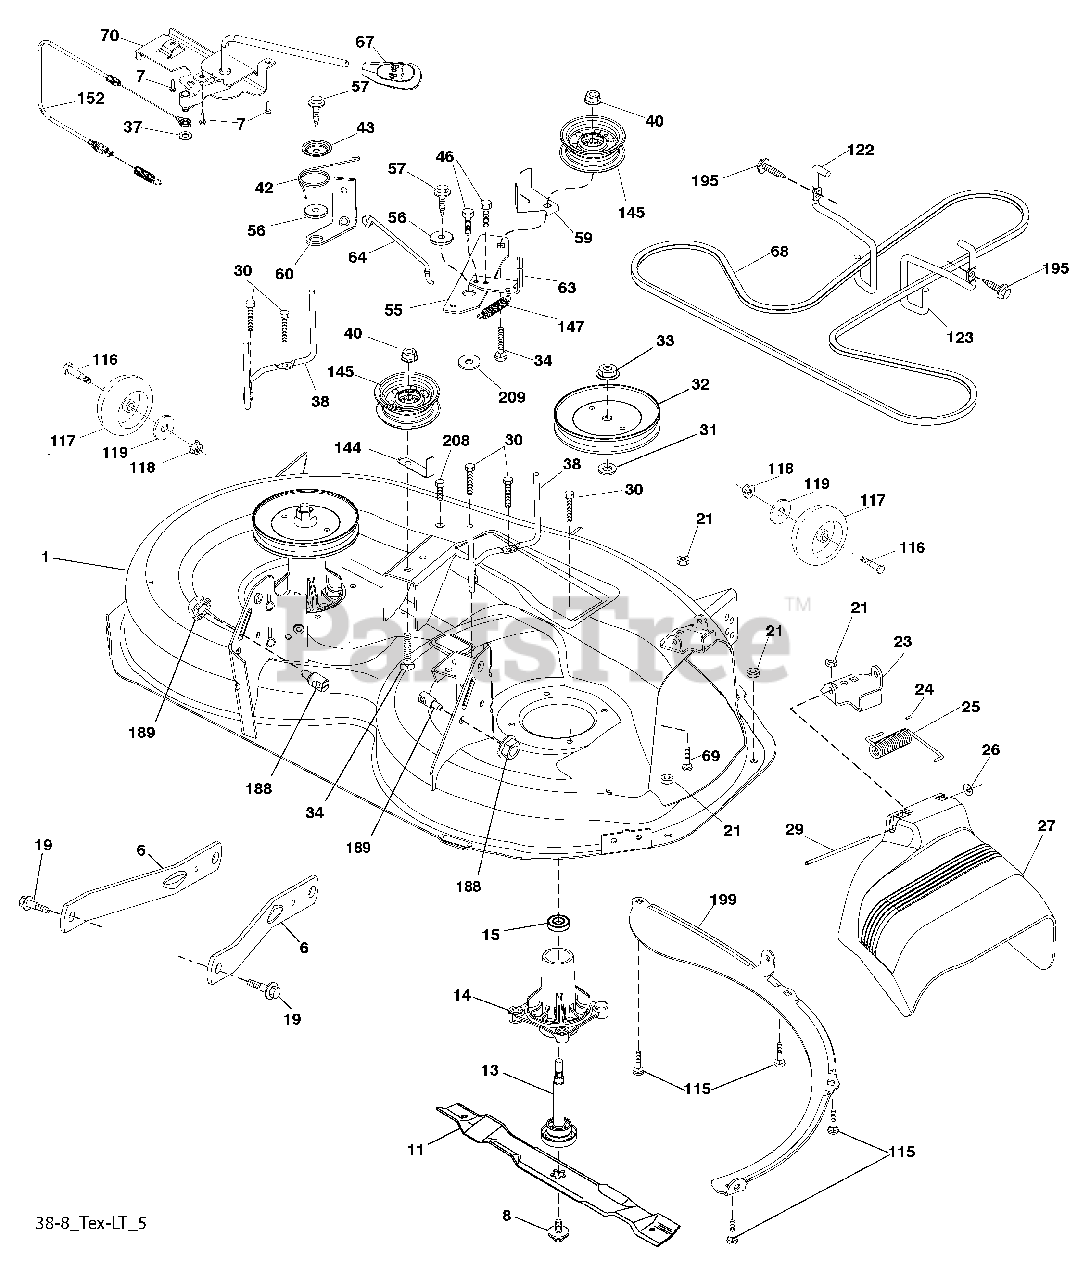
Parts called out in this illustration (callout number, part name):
1	Mower Housing
6	Arm Suspension
7	Screw #10 x 0.750 BOS Thread
8	Bolt/Washer asm 7/16-20 unf
11	Blade 38" 3N1 PREMIUM
13	Shaft Assembly, Mandrel
14	Housing, Mandrel
15	Bearing, Ball, Mandrel
19	Bolt, Shoulder
21	Nut, Crownlock 5/16-18 unc
23	Bracket, Deflector
24	Cap, Sleeve
25	Spring, Torsion, Deflector
27	Shield, Deflector
29	Rod, Hinge
30	Screw Thdrol Rolling Wsh Hd
31	Washer, Spacer
32	Pulley, Mandrel
33	Nut, Toplock, Flanged
34	Bolt Carr Sh. 3/8-16 x 1-1/2 Gr. 5
37	Washer
38	Keeper Belt LH Mandrel
40	Nut, Lock Flg. 3/8-16 unc
42	Spring Torsion Brake
43	Spring Torsion Retainer
46	Screw 1/4-20 x 5/8
55	Arm, Idler
56	Spacer, Retainer
57	Screw 3/8-16 x 1
59	Guard, Tuv Idler
60	Arm Brake Mower LH
63	Arm Brake Mower RH
64	Link Brake
67	Handle Clutch Cable
69	Bolt
70	Clutch Asm Manual
115	Bolt Carr. 5/16-18 x 5/8
116	Bolt, Shoulder
117	Wheel, Gauge
118	Nut Lock 3/8-16 unc
119	Washer 3/8 x 7/8 x 14 Ga.
122	Keeper Belt Engine LH
123	Keeper Belt Engine RH
144	Keeper Belt
145	Pulley Idler
147	Spring Return
152	Manual Clutch Cable
188	Stud Fastener
189	Nut Lock Hex Flange
195	Screw 3/8-16 x 3/4
199	Baffle Vortex
208	Screw Thdrol 3/8-16 x 1/2
209	Washer 13/32 x 2 x 10
